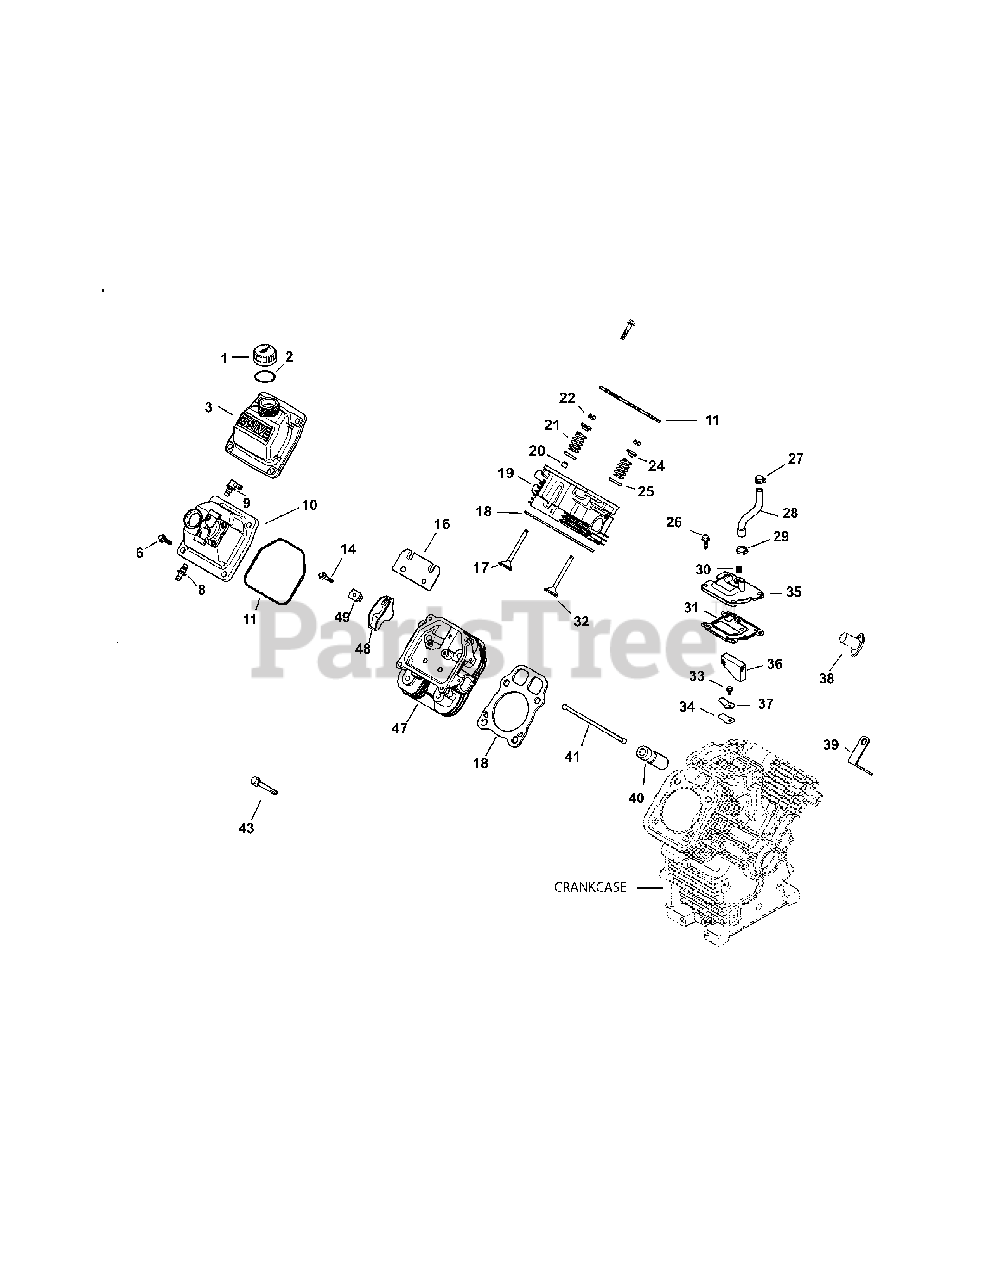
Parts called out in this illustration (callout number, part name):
1	Kit, Oil Fill Cap (Yellow)
2	O-Ring, Dipstick
3	Kit, Valve Cover-Oil Fill
6	Screw, Flg M6X1.0X30
8	Kit, 1/4" Fitting (Straight)
9	Kit, 90 Deg. Fitting
10	Kit, Valve Cover-Fuel Pump
11	O-Ring (Yellow), Valve Cover
14	Screw, Flg M6X1.0X34
16	Kit, Valve Train
17	Valve, Exhaust (Std)
17	Valve, Exhaust (.25)
18	Kit, Cyl Head Gasket (C17-22)
19	Kit, #1 Cyl Head Assy
20	Seal, Valve Stem
21	Spring, Valve
22	Kit, Retainer
24	Cap, Valve Spring
25	Retainer, Spring
26	Screw, Thread Forming
27	Clamp, Band Spring Hose
28	Hose, Breather
30	Plug, Pipe CTSK 1/8"
31	Gasket, Breather
32	Valve, Intake (Std)
32	Valve, Intake (.25)
33	Screw, Flg Thd Frm M5X.8X10
34	Reed, Breather
35	Kit, Breather Assy
36	Filter, Breather
37	Retainer, Reed
38	Screw, Thread Forming
40	Hydraulic Valve Lifter
43	Screw, Flg M10X1.5X90
47	Kit, #2 Cyl Head Assy
49	Pivot, Rocker Arm
